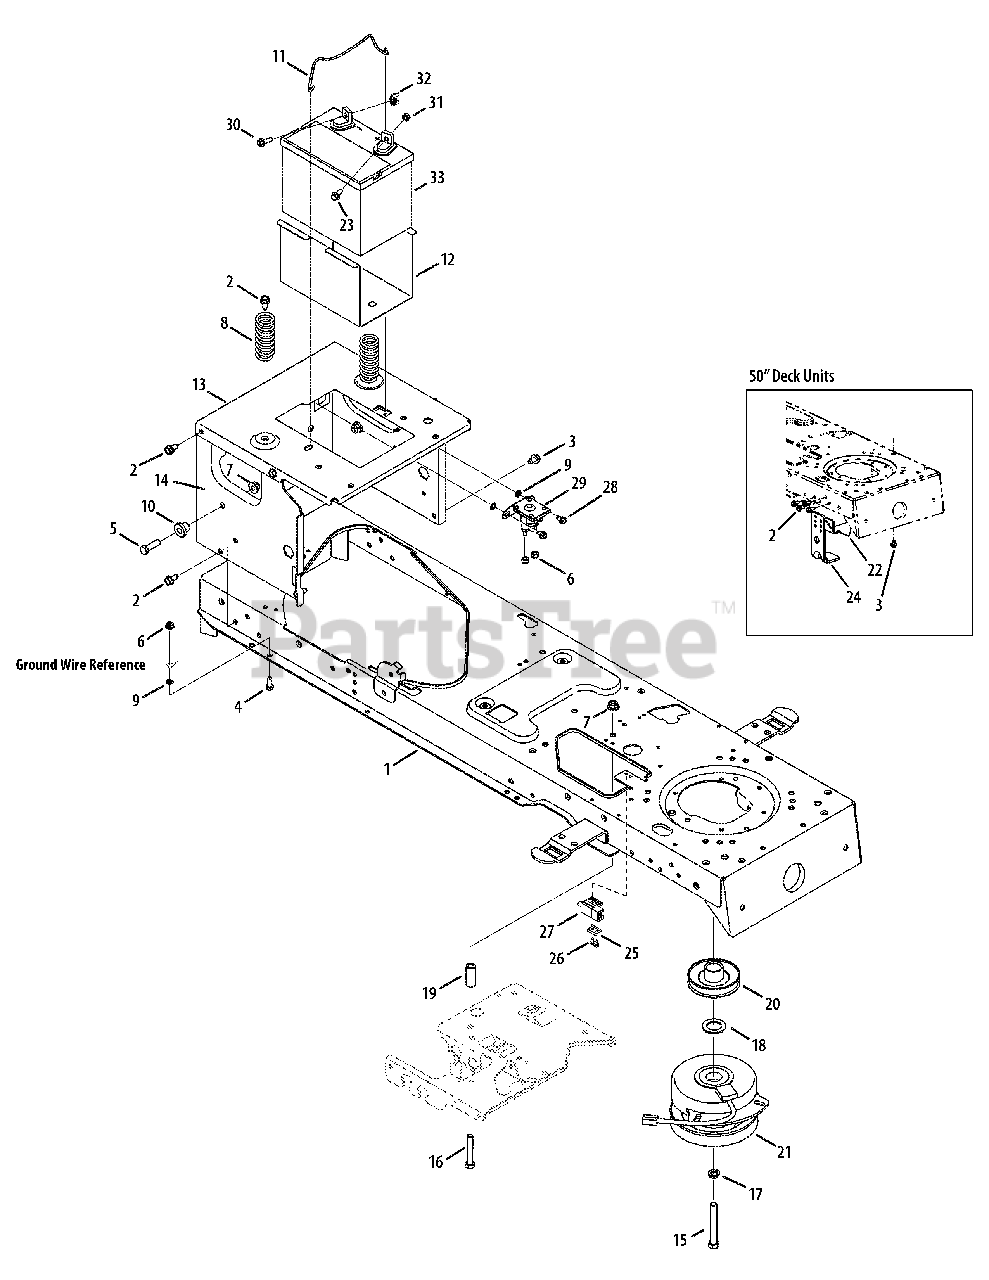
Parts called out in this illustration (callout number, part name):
3	Screw, 5/16-18, 0.500
4	Screw, 1/4-20, 0.750
5	Screw, 3/8-16, 1.25, Gr5
6	Nut, Flange Lock, 1/4-20
7	Nut, Flange Lock, 3/8-16
8	Spring, Compress., 1.28 x 3.125
9	Washer, Lock, 1/4, External
10	Spacer, Shoulder,.38 x 1.0 x.70
11	Hold Rod, Battery
15	Screw, 7/16-20, 3.50, Gr5, Lock
16	Screw, 3/8-16, 2.25, Gr5
17	Lock Washer, 7/16
18	Washer, Flat, 1.031 x 1.620 x.095
19	Spacer,.385 ID x.635 OD x 1.54
20	Pulley, Engine, 3.56 Diameter
21	PTO Clutch, Electric
23	Screw, Shoulder,.250 x.15, 1/4-20
25	Switch Plate
26	AB Screw, #10-16 x.500
27	Switch
28	Screw, 1/4-20, 0.50
29	Solenoid, 12V, 100 Amp
30	Hex Flange Bolt, 1/4-20,.75
31	Nut, Sems, 1/4-20
32	Nut, Wing, 1/4-20
33	Battery, 235 CCA
